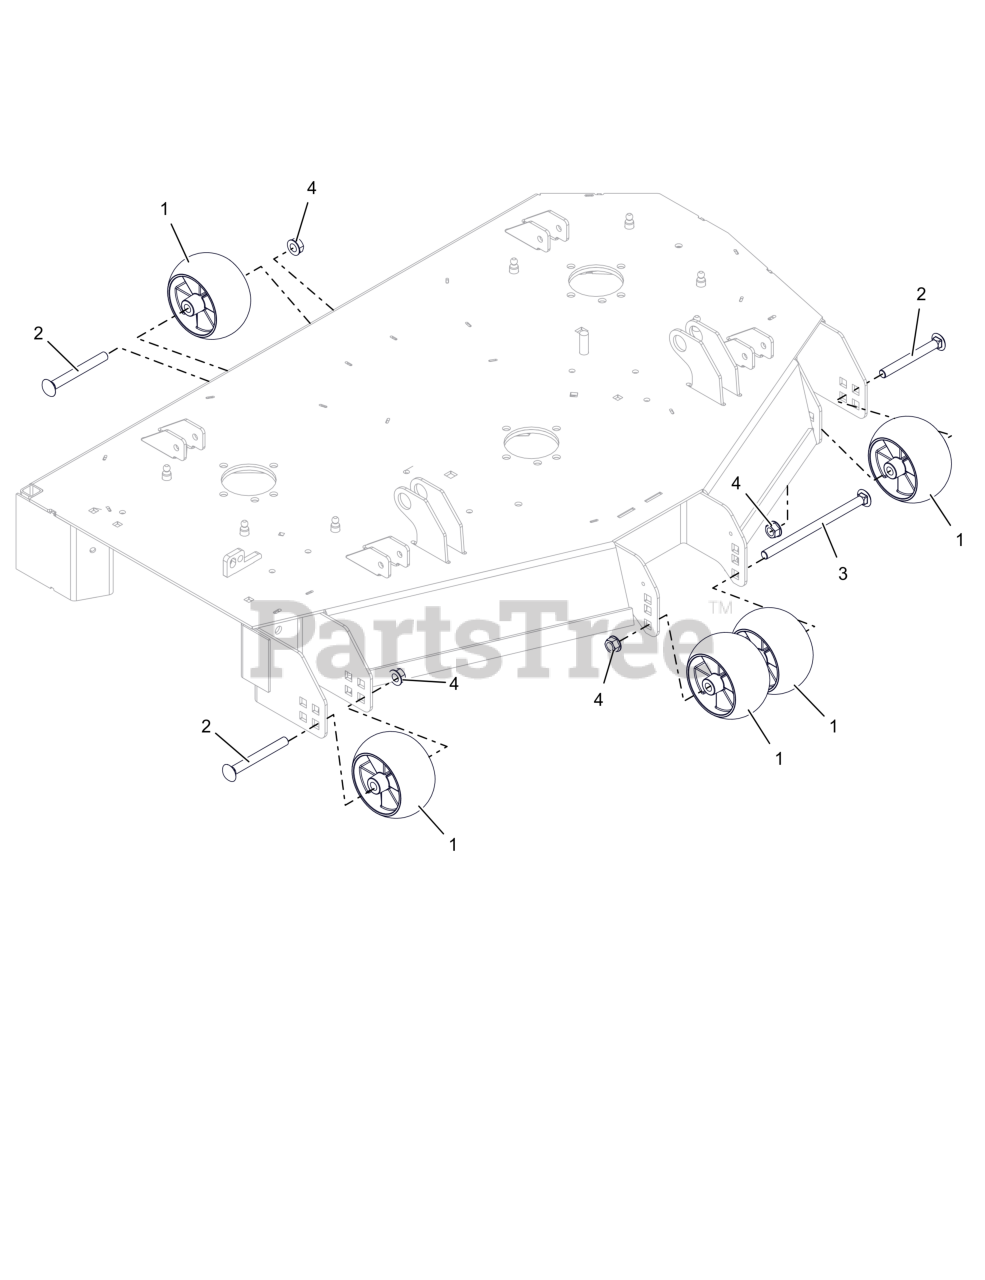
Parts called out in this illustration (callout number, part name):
1	WHEEL, ANTI SCALP - 5X3 CTR W/RIBS
2	BOLT, RHNS .50-13X4.50 G5 ZCC NS
3	BOLT, RHNS .50-13X8.00 G5 ZCC NS
4	NUT-LK-CTR-FLG .500-13 GG ZCC
